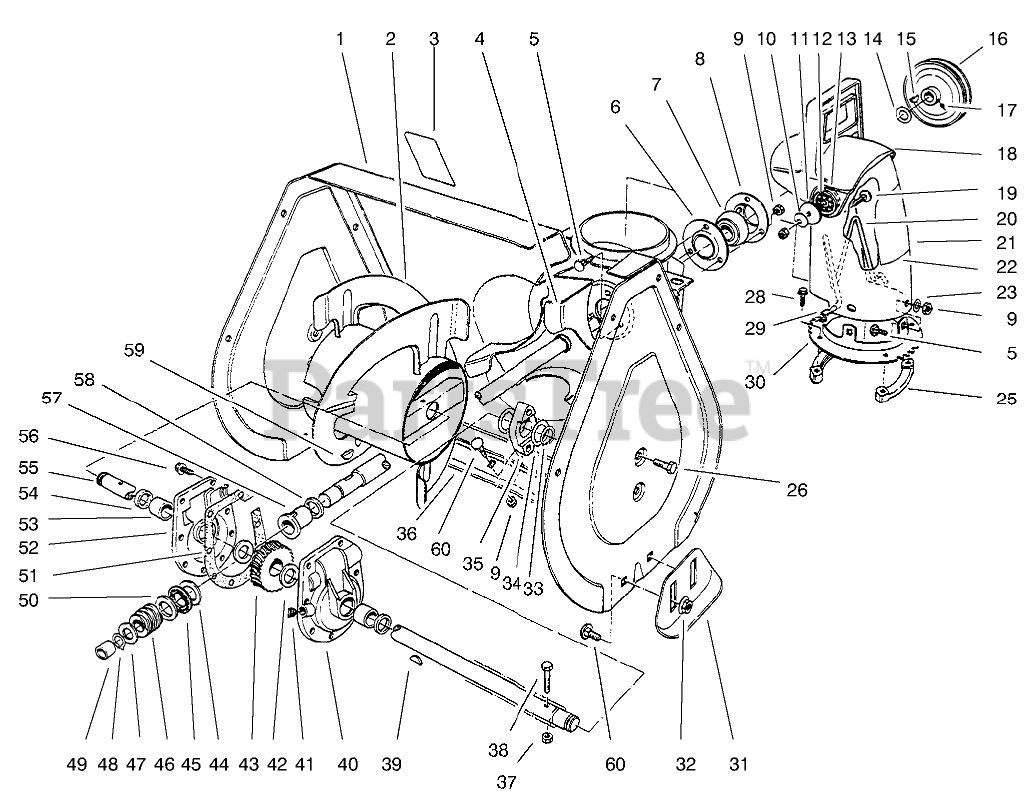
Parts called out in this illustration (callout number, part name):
1	Housing-Auger (Model No. 38072)(Incl. Ref. #3)
2	Auger-R.H.
3	DECAL-WARNING, AUGER
4	Shaft & Impeiler
5	SCREW-CARR
6	Flange-Bearing Front
7	BEARING-BALL
8	Flange-Bearing Rear
9	NUT-LOCK, NI
10	WASHER-BELLEVILLE
11	WASHER-FLAT
12	PLATE-FRICTION
13	WASHER-RUBBER
14	WASHER
15	KEY-WOODRUFF
16	PULLEY
17	SCREW-SET, SQH
18	CHUTE-DEFLECTOR
19	SCREW-CARR
20	WIRE-CHUTE
21	Chute-Discharge (Model No. 38072)(Incl. Ref. #22)
22	Decal-Danger
23	WASHER-PLAIN
25	RING-CHUTE, RETAINER
26	SCREW-HWHTF
28	SCREW-SPECIAL
29	NUT-PUSH
30	Chute Ring
31	Skid
32	NUT-HF
33	RING-RETAINING
34	WASHER
35	BEARING-AUGER
36	Blade-Scraper
37	NUT-LOCK, NI
38	SCREW-HH
39	KEY-WOODRUFF
40	Gear Case L.H. (Incl. Ref. #53 & 54)
41	PLUG-PIPE, SQH
42	WASHER-THRUST
43	GEAR-WORM, 27T
44	WASHER-THRUST
45	BEARING-THRUST
47	WASHER-THRUST
48	Ring-Snap
49	BUSHING
50	WASHER-THRUST
51	GASKET-CASE, GEAR
52	Gear Case R.H. (Incl. Ref. #53 & 54)
53	BUSHING
54	SEAL-OIL
55	SHAFT-AUGER
56	SCREW-TAPTITE
57	BUSHING-INPUT
58	RING-QUAD
59	KEY-WOODRUFF
60	BOLT-CARR
